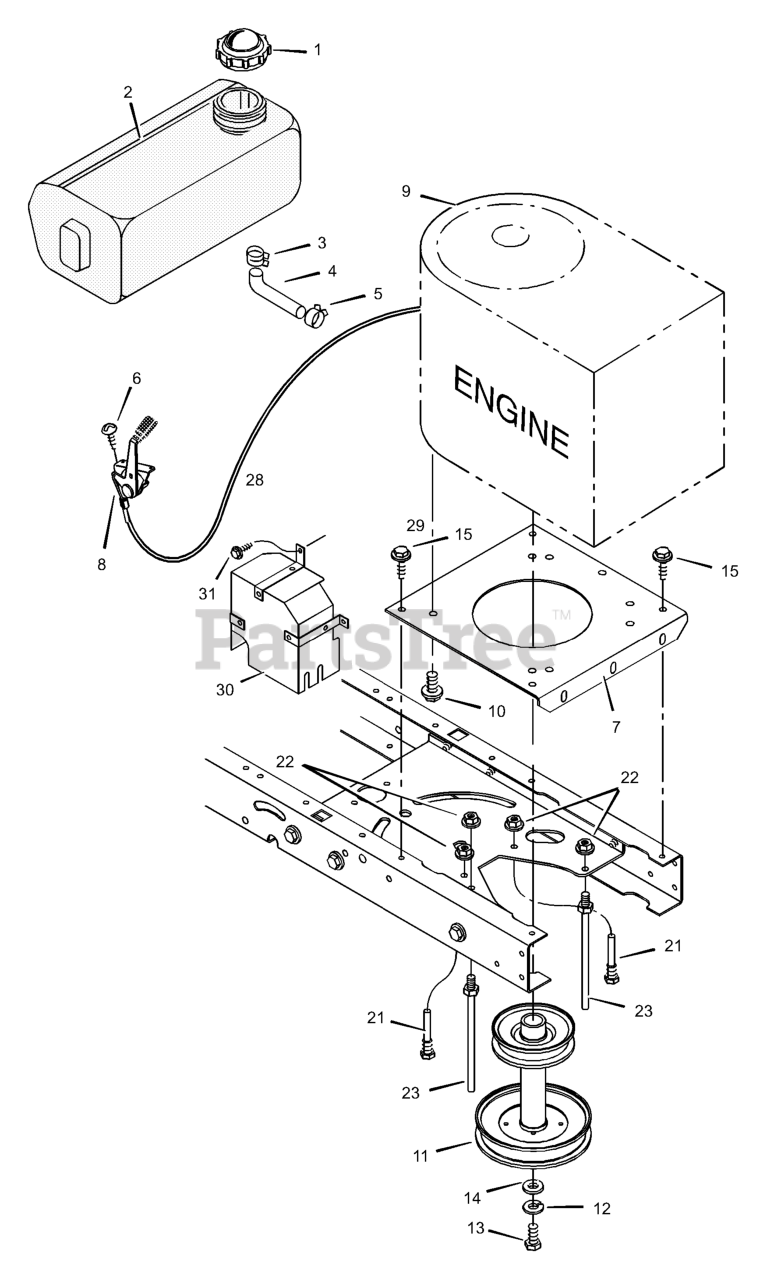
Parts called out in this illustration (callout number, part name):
1	Fuel Cap
2	Fuel Tank
3	Hose Clamp
4	Fuel Line (Must cut to length)
5	Hose Clamp
7	Plate, Engine
8	Throttle Control
9	Engine
10	Bolt, Engine Mount
11	STACK PULLEY ASSEMBLY
12	Lockwasher
13	Bolt, Hex
21	Guide, Belt
22	Nut, Flange
23	Guide, Belt
30	Shield, Heat
